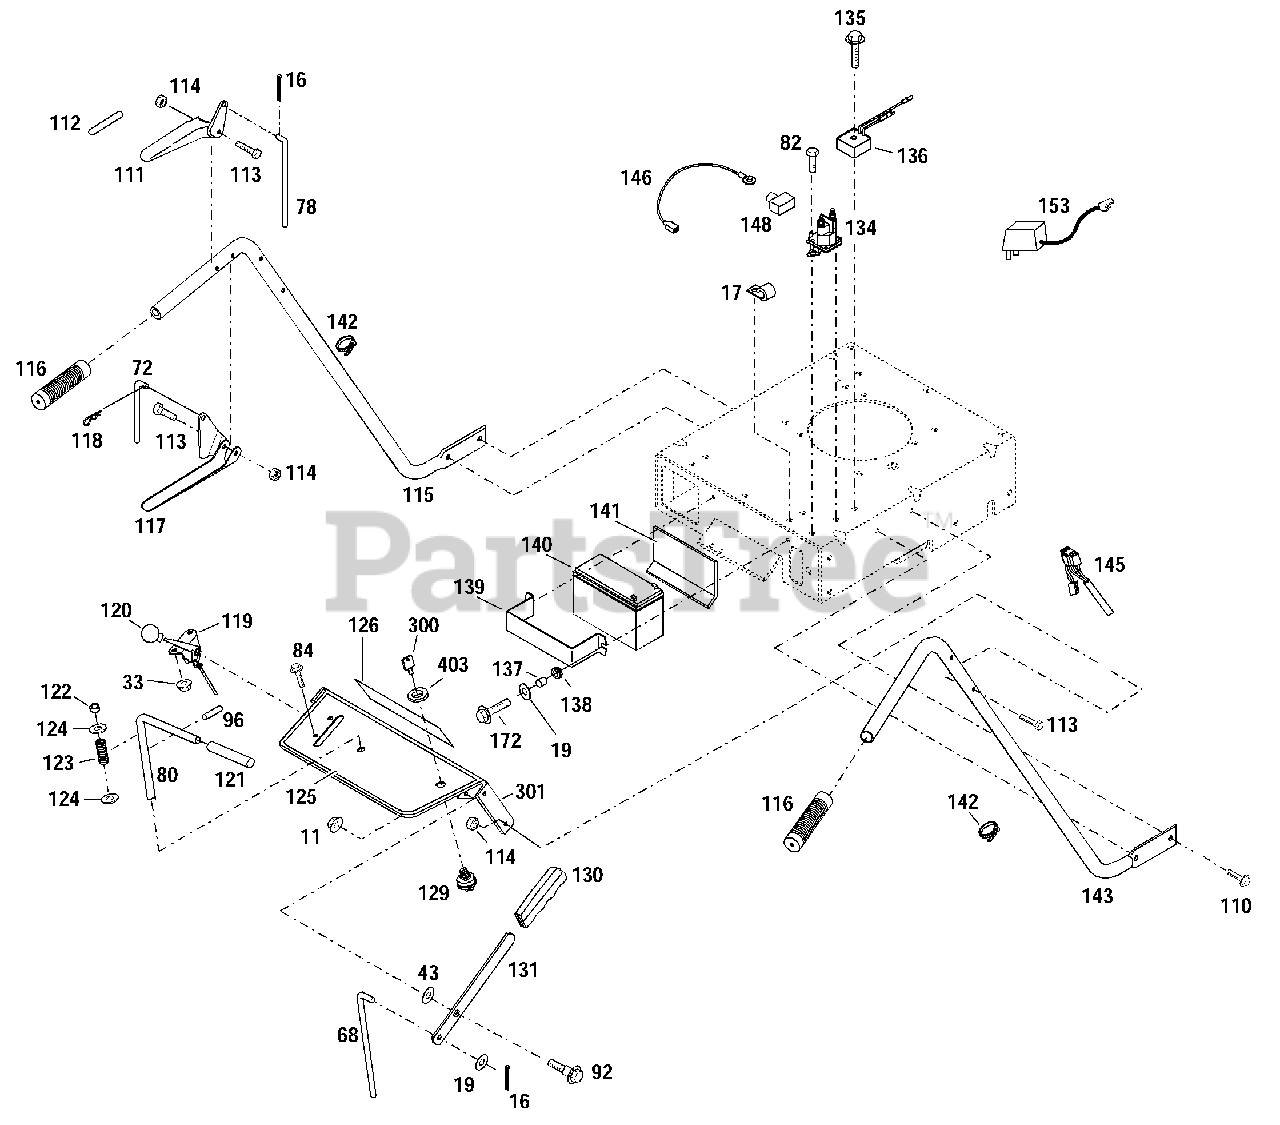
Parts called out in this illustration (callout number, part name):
11	Flange Locknut, 3/8-16
16	Cotter Pin, 3/32 x 5/8
17	J-Clip
19	Flat Washer, 5/16
33	Flange Locknut, 1/4-20
43	Flat Washer, 1/2
68	Upper Blade Rod
72	Upper Transmission Rod
78	Upper Brake Rod
80	Shift Rod
82	Thread Cut. Screw, 1/4-20 x 1/2
84	Flange Lock Screw, 1/4-20 x 1/2
92	Shoulder Bolt
96	Roll Pin, 1/4 x 2-1/4
110	Flange Lock Screw, 5/16 x 3/4
111	Control Handle
112	Operator Presence Control Decal
113	Screw, 1/4-20 x 1-3/4, Grade 8
114	Locknut, 1/4-20
115	Left Handlebar
116	Handle Grip
117	Control Handle
118	Hair Pin, 5/64
119	Throttle Control
120	Knob
121	Handle Grip
122	Nylon Bushing
123	Compression Spring
124	Flat Washer, 1/2
125	Warning Decal
126	Logo Decal
129	Ignition Switch
130	Handle Grip
131	Mower Engage Lever
134	Solenoid
135	Thread-Cut. Screw, 1/4-20 x 1-1/2
136	Regulator
137	Spacer
138	Grommet
139	Battery Bracket
140	Battery
141	Battery Pad
142	Plastic Tie
143	Right Handlebar
145	Wiring Harness
146	Lead
148	Boot
153	Battery Charger (shipped loose)
172	Screw, 5/16-18 x 3/4
300	Ignition Key
301	Console Assembly
403	Nut, Ignition Switch
